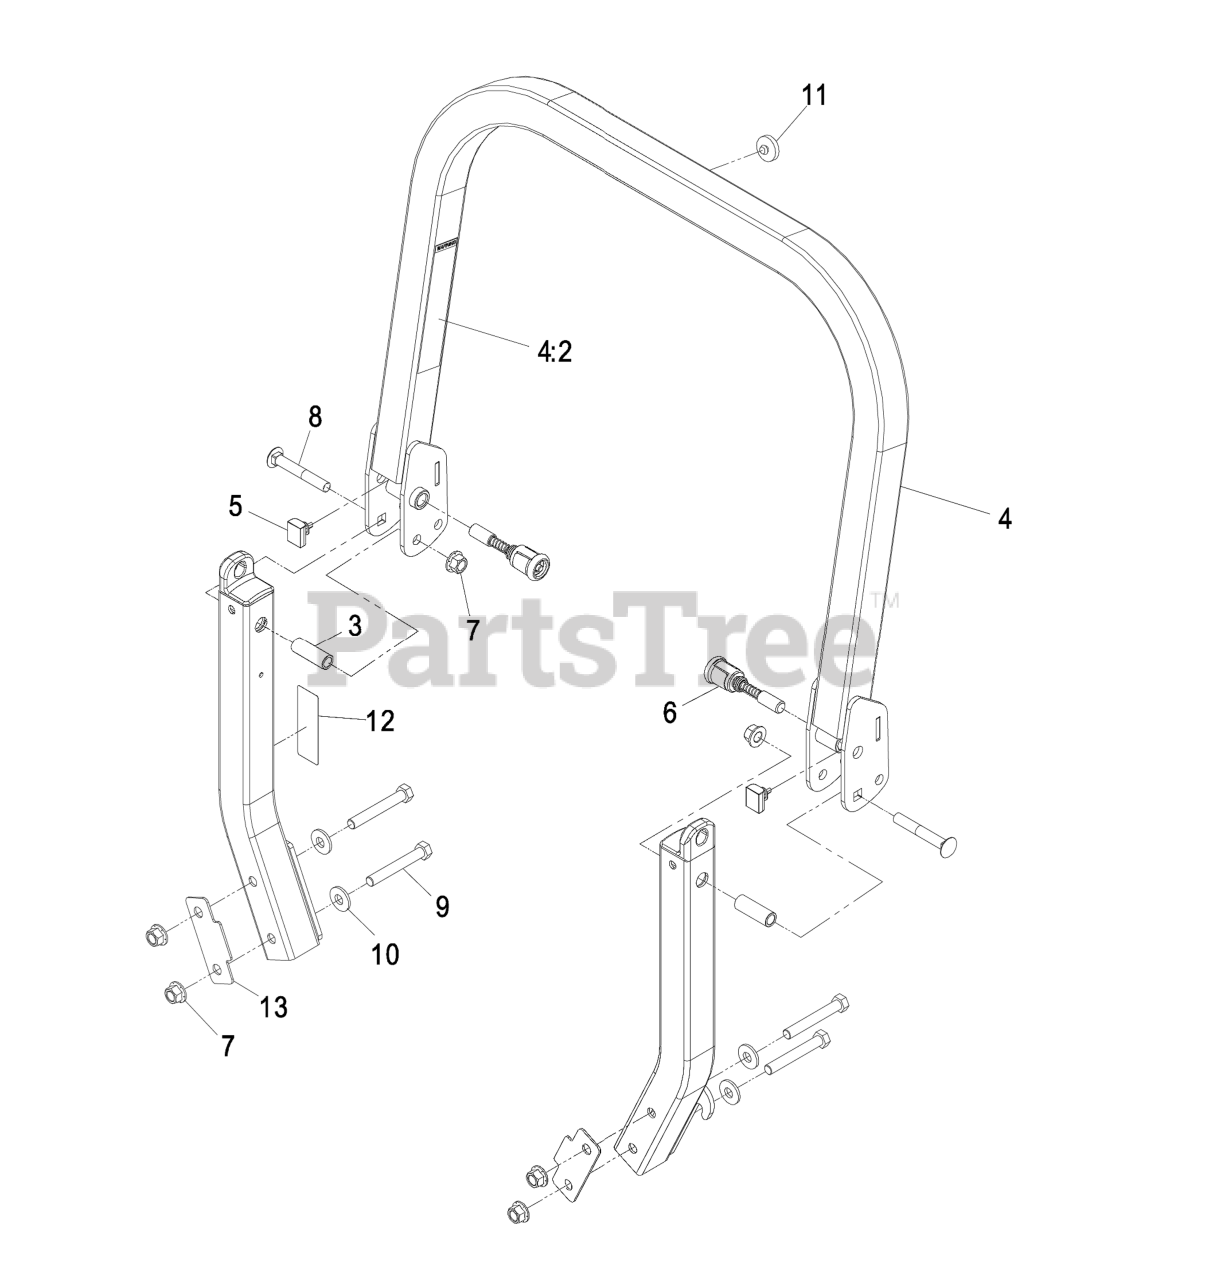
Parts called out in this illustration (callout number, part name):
4	UPPER ROPS ASM
4:2	DECAL-WARNING, FOLDING RO
5	BUMPER-ROPS
6	PIN-SPRING
7	Nut-Lock 1/2-13
8	SCREW-CARR
9	SCREW-HH
10	WASHER-SPRING
11	BUMPER-PUSH-IN, RUBBER
12	DECAL-CAUTION
